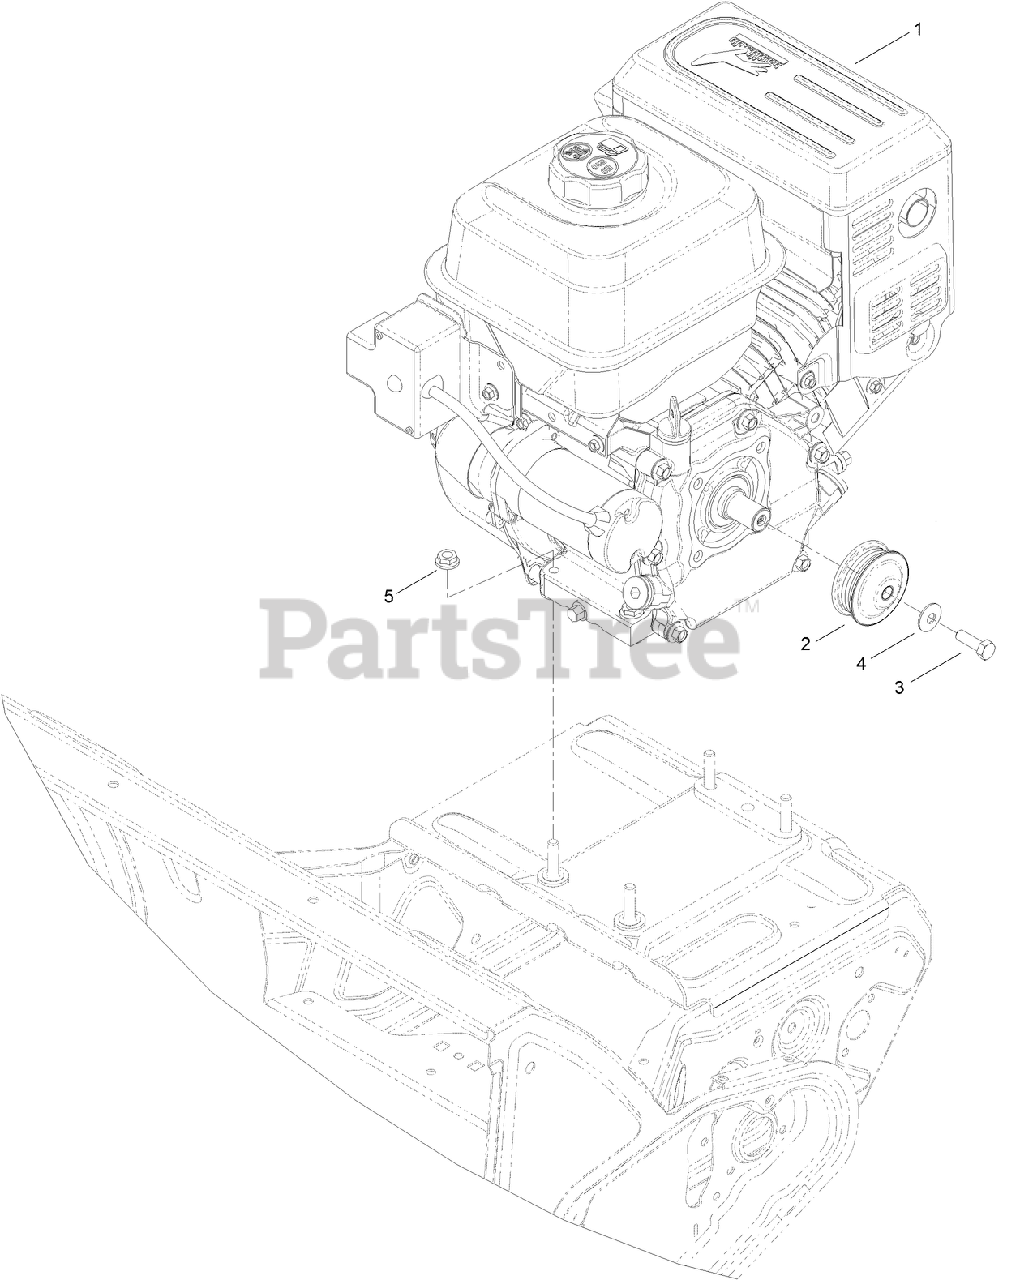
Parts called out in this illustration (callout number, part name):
1	ENGINE-G210FDS-2
2	PULLEY-ENGINE
3	SCREW-HH, PATCH
4	WASHER-BELLEVILLE
5	NUT-HF
